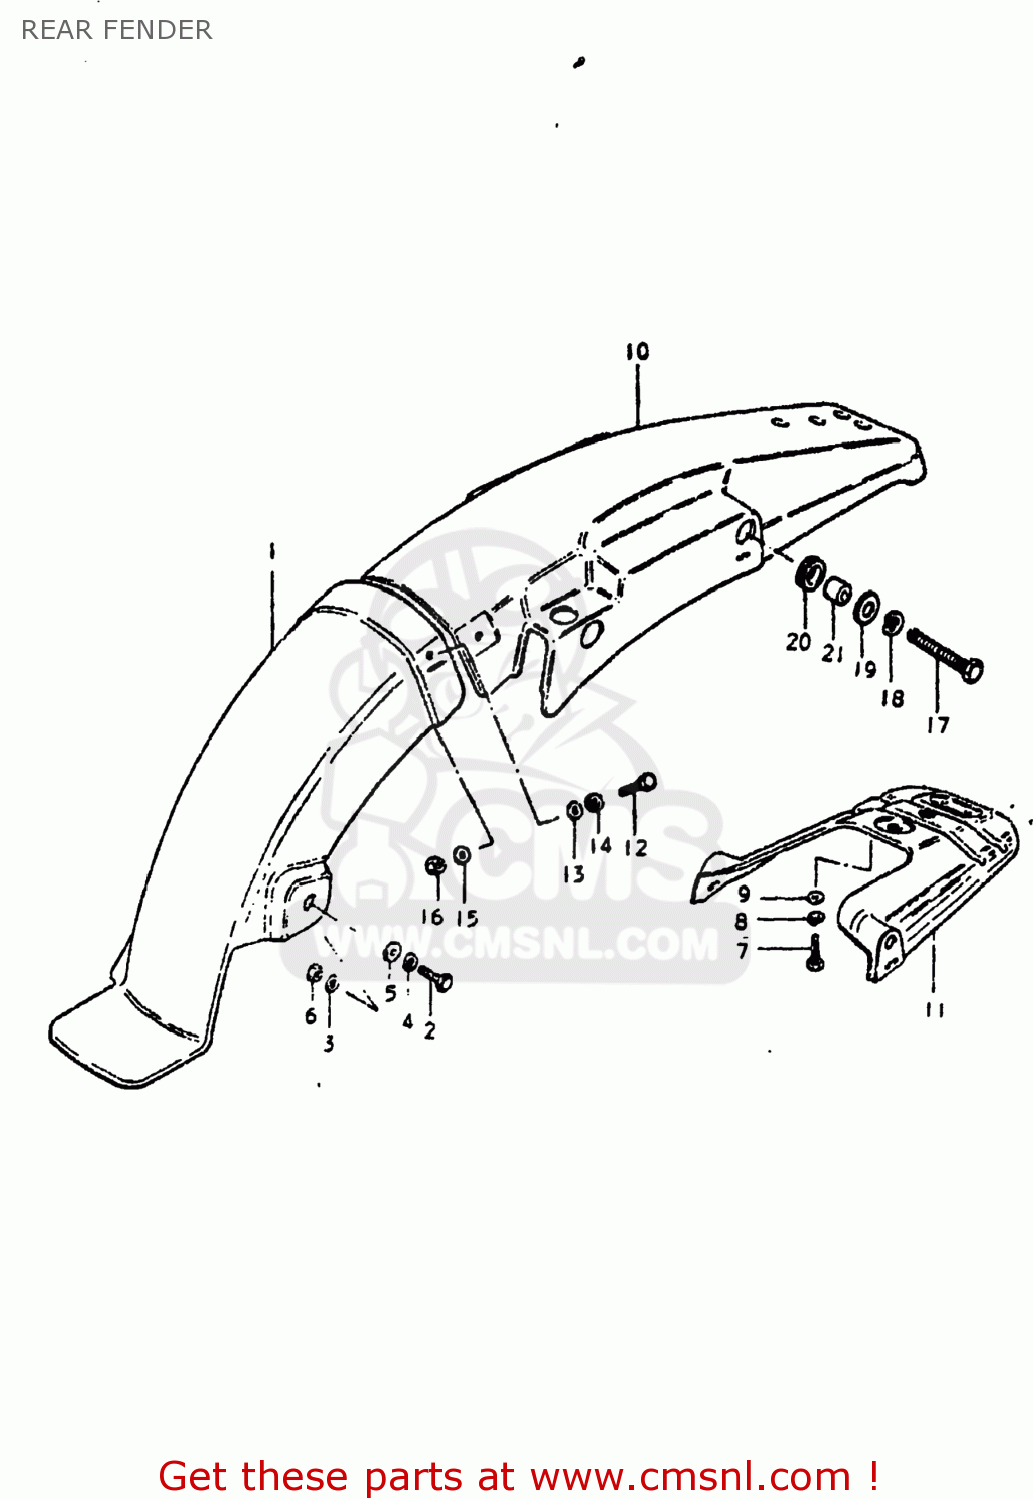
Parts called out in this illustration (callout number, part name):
1	FENDER,REAR
2	BOLT, UPPER
3	WASHER
4	LOCK WASHER
5	WASHER
6	NUT
7	BOLT
8	LOCK WASHER
9	WASHER
10	FENDER,REAR
11	REINFORCEMENT,REAR FENDER
12	BOLT
13	WASHER (5.5X16X1.2)
14	LOCK WASHER
15	WASHER(5.2X16X1)
16	NUT
17	BOLT
18	LOCK WASHER
19	WASHER
20	CUSHION
21	SPACER (8.2X12X7.5)
